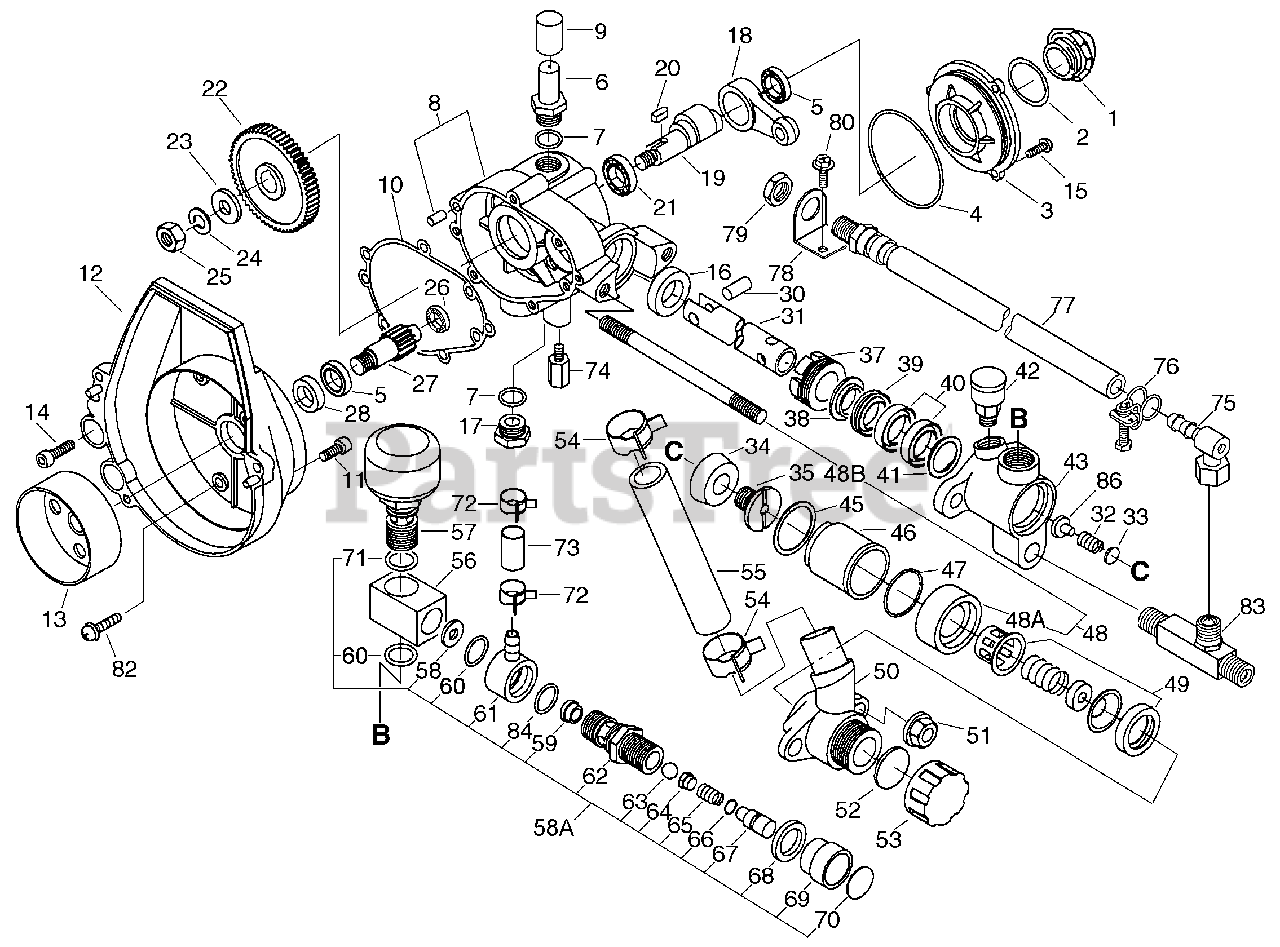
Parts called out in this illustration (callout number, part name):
1	GAUGE, OIL
3	LID, GEAR CASE
5	BEARING, BALL - 6001
8	PUMP BODY ASSY
11	SCREW - 5X18
12	COVER, FAN
13	DRUM, CLUTCH
14	SCREW - 5X25
15	SCREW - 4X12
16	SEAL, OIL
17	CAP, DRAIN
18	ROD, CONNECTING
19	CRANKSHAFT
21	BEARING, BALL - 6201
22	GEAR - SPUR
23	WASHER - 8
24	LOCKWASHER - 8
26	BEARING, BALL - 609
27	SHAFT, PINION
28	SEAL, OIL
30	PIN, PISTON
31	PLUNGER ASSY
32	VALVE SPRING
33	DISK, VALVE
34	SEAL, PISTON
35	SEAT, VALVE
37	NUT - GLAND
38	SEAL, GREASE
39	SEAL, GREASE
40	SAEL SET
42	CUP, GREASE
43	CYLINDER
48	VALVE CASING ASSY
48A	CASING, VALVE
49	VALVE ASSY
50	PIPE, INTAKE
52	GASKET, DRAIN
53	CAP, DRAIN
55	HOSE - SUCTION
56	CONNECTOR
57	CHAMBER, AIR
58A	REGULATOR ASSY
59	SEAT, VALVE
60	O-RING - 16
61	CASING, VALVE
62	CASING, SPRING
63	VALVE, BALL
64	SEAT, SPRING
66	O-RING - 7
67	SEAT, SPRING
69	CAP, REGULATOR
70	LABEL - REGULATOR
71	O-RING - 12.5
73	HOSE - RETURN
77	HOSE
79	NUT
80	SCREW - 5X14
82	SCREW - 5X25
83	CONNECTOR
86	SEAT, SPRING
